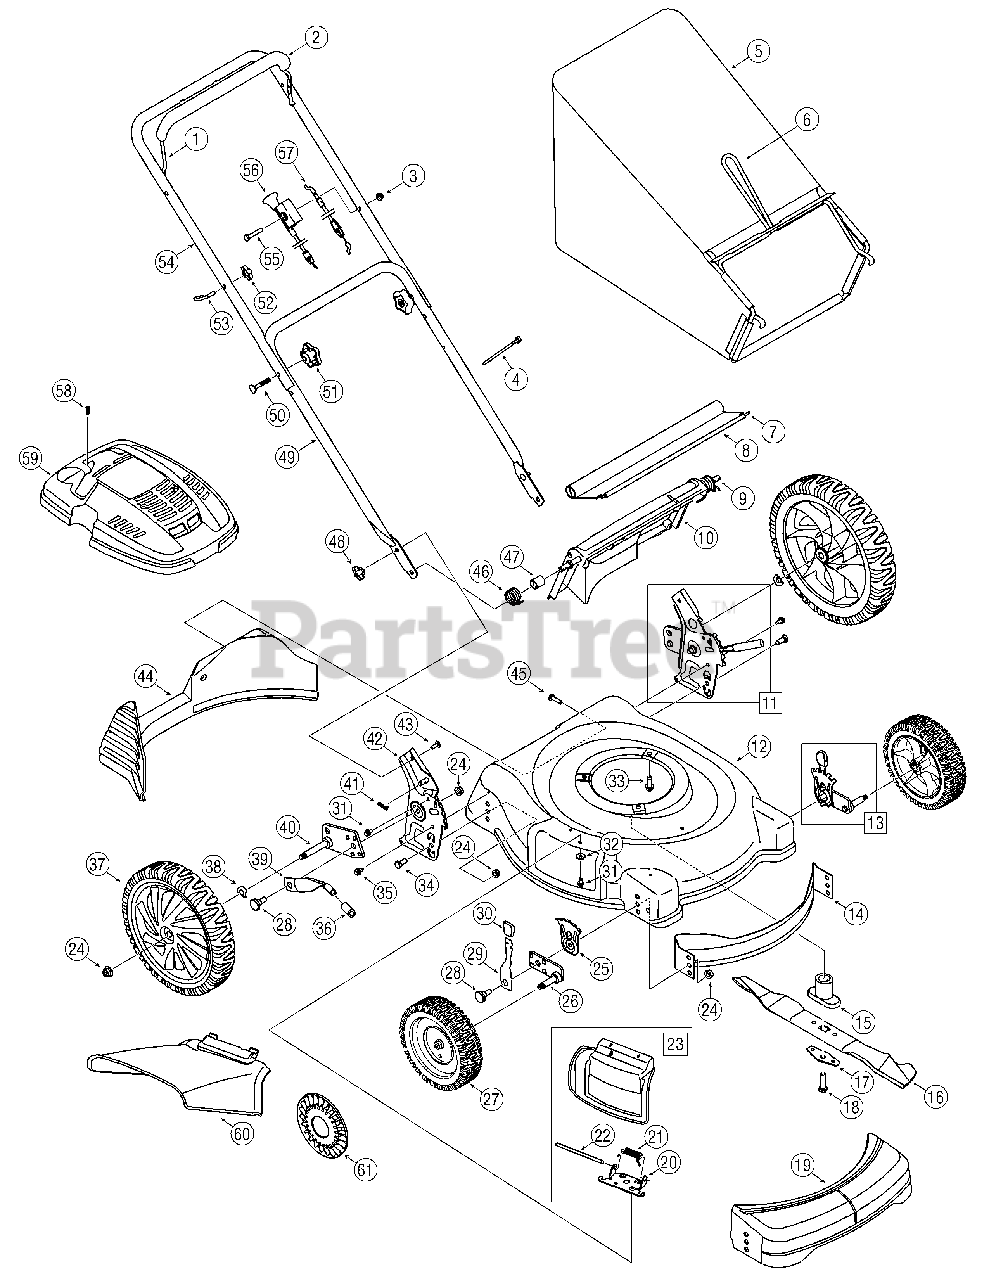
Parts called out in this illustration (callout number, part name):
3	Flange Lock Nut 1/2-20
4	Cable Tie
5	Grass Bag Assembly
7	Trailshield Wire
10	Rear Discharge Door
11	Rear Handle Bracket Assy. - LH
14	Front Baffle
15	Blade Adapter
16	21-inch Mulching Blade
17	Bell Blade Support
18	Hex Screw, 3/8-24 x 2.5
20	Chute Deflector Adapter
21	Torsion Spring
22	Hinge Pin
23	Hinged Mulch Plug Assembly
24	Flange Lock Nut 3/8-16
25	Height Adjustment Plate
26	Front Pivot Arm Assembly - RH
27	Front Wheel, 8 x 2.125 Zag
28	Shoulder Screw, .5D x .434
29	Front Spring Lever
30	Height Adjust Knob
31	TT Screw, 1/4-20 x .500
33	TT Screw, 3/8-16 x 1.0
34	Hex Screw, 3/8-16 x .75
35	TT Screw, 1/4-20 x .625
37	Rear Wheel, 12 x 2.125 S
38	Spring Washer
39	Rear Hi-Wheel Spring Lever
40	Rear Pivot Arm Assy - RH
41	Hairpin Clip
42	Handle Bracket Assy - RH
42	Handle Bracket Assy - LH
43	Carriage Bolt ,1/4-20 x .75
45	Screw HL, 1/4-15 x 1.00
46	Torsion Spring - RH
47	Spacer
48	Wing Nut
50	Carriage Bolt, 5/16-18 x 2
51	Star Knob
55	Hex Screw, 1/4-20 x 1.50
56	Cable, Choke 38-inch
57	Cable, ERS 48-inch
58	Machine Screw M4-.7x10.00
59	Engine Shroud
60	Side Discharge Chute
61	Hub Cap, Radial Spoke
